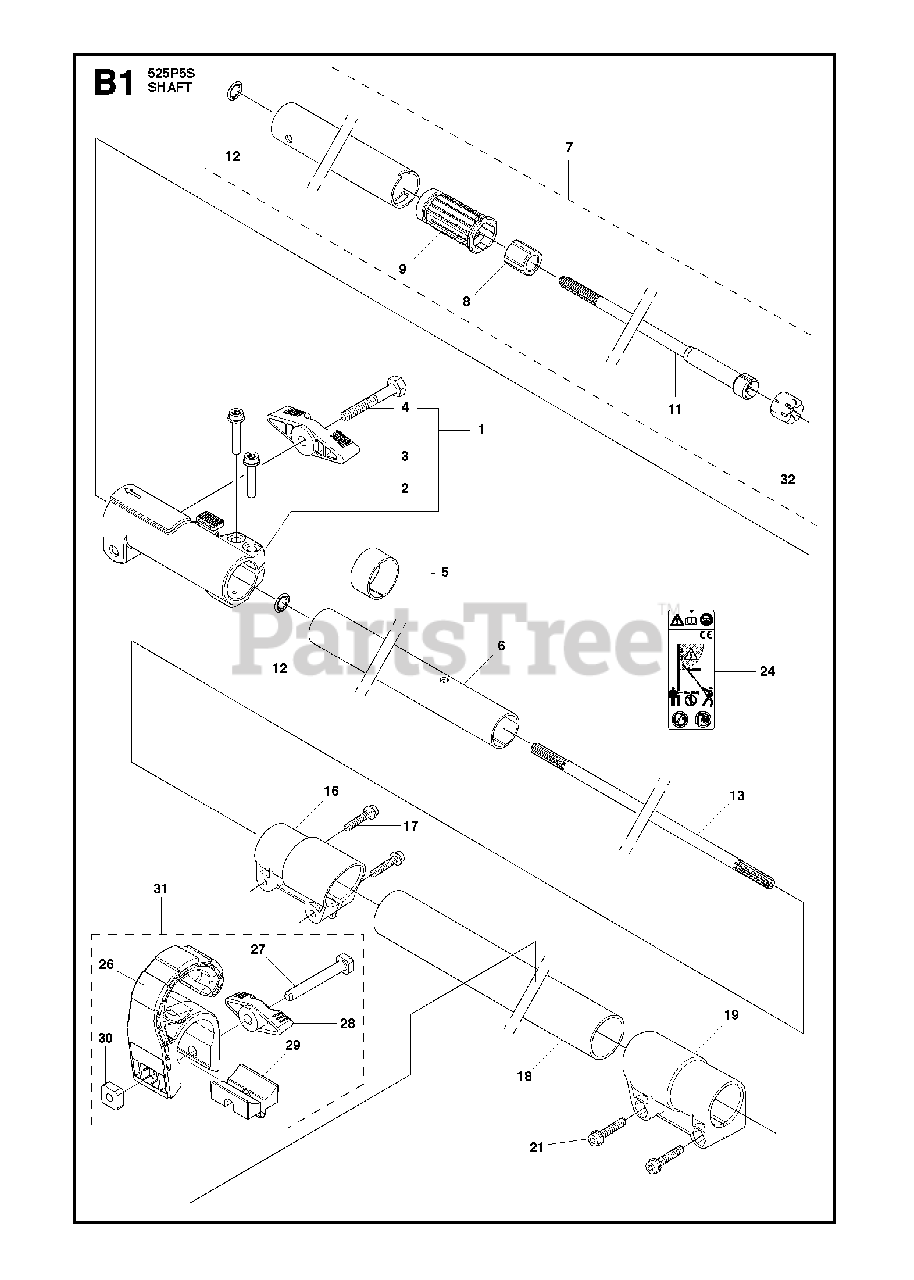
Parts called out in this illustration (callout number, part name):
1	CLAMPING SLEEVE ASSY
2	SCREW
3	KNOB CLAMPING SLEEVE
4	BOLT FLANGE
6	TUBE ASSY INNER SPARE PART
7	TUBE
8	BUSHING
9	PLUG
11	DRIVE SHAFT
12	WASHER
13	DRIVESHAFT
16	LOCKING SLEEVE
18	PIPE
19	LOCKING SLEEVE
24	DECAL WARNING SPARK ARRESTOR
26	LOOP 30MM
27	SCREW
28	HANDLE
29	SPACING BLOCK 30
30	NUT
31	ACCESSORY BAG
